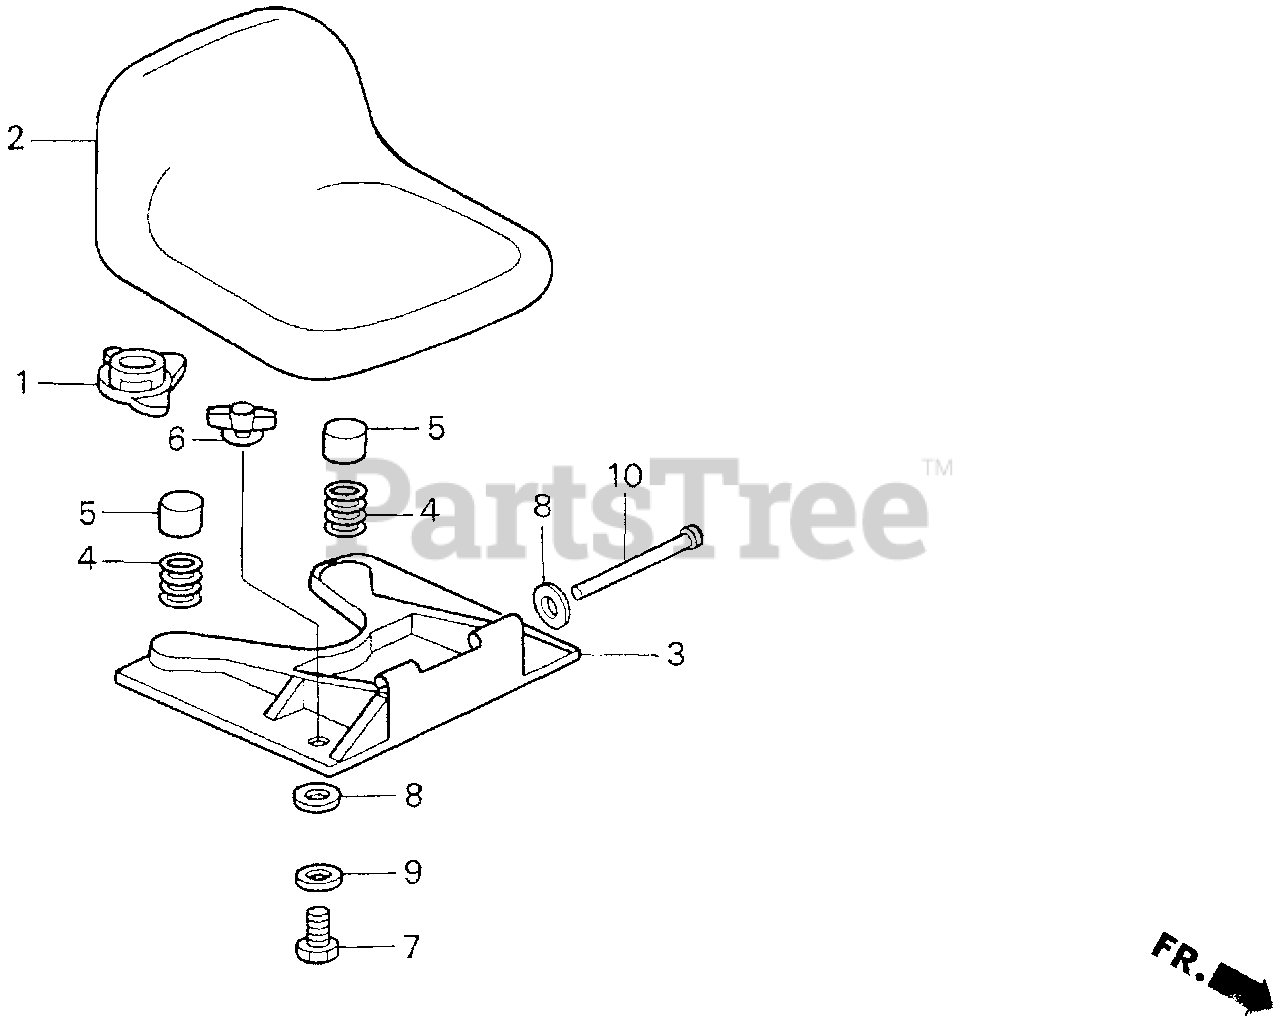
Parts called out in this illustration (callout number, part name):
1	SWITCH ASSY., SEAT
2	SEAT ASSY.
3	BASE, SEAT
4	SPRING, SEAT
5	CAP, SEAT SPRING
6	GRIP, SEAT
7	BOLT, HEX. (3/8")
8	NUT, SEAT BASE PUSH
9	WASHER, FENDER FLAT
10	PIN, SEAT PIVOT
